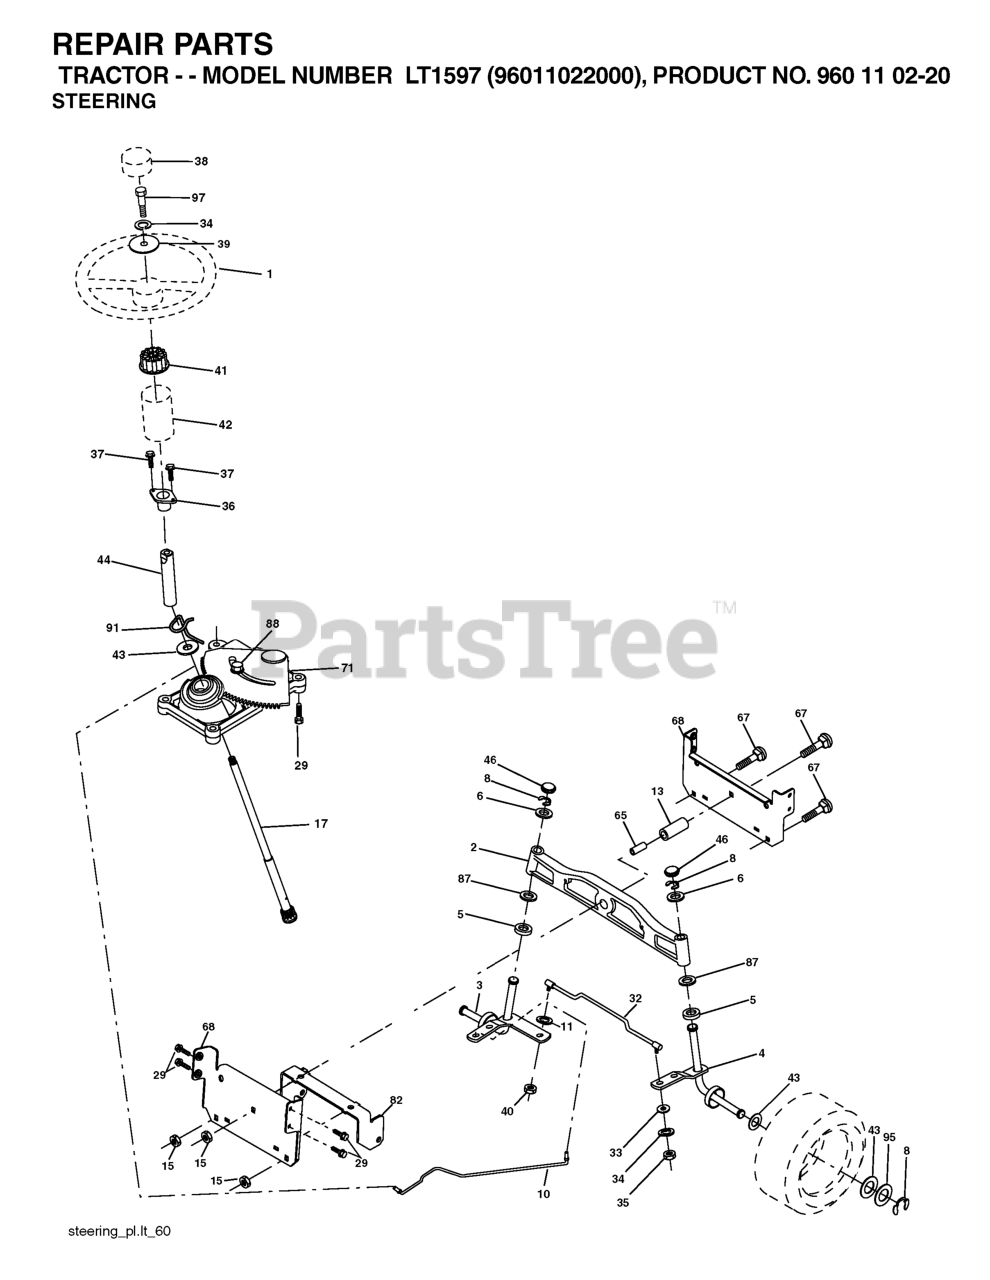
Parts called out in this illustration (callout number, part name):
1	WHEEL.STEERING.LEGEND2.GRY
2	AXLE ASSY FRONT
3	SPINDLE.ASM.LH.15"TIRES
4	SPINDLE.ASM.RH.15"TIRES
5	THRUST WASHER
9	BRNG T
10	DRAGLINK.15".TIRES.2001
11	WASHER, LOCK 3/8
13	TUBE, PIVOT AXLE
15	NUT
17	SHAFT STEERING SPLINE
29	SCREW, 3/8-16X3/4
33	WASHER M
34	WASHER.LOCK.HVY.HLCL.SPR.5/16
35	NUT, CROWNLOCK
36	BUSHING, STEERING
37	SCREW.TT.#10-32X.5.3/8.FLANGE
38	INSERT.CAP.STRG.WH.GRAY
39	WASHER.11/32
40	NUT CROWNLOCK 3/8-24
41	ADAPTER, WHEEL STNG..
42	BOOT STEERING
44	SHAFT.EXTEN.STRG.SPLINE
46	CAP.SPINDLE.BLACK
47	FITTING.GREASE.TAPERED
65	SPACER BRACE AXLE
67	BOLT CARRIAGE
68	BRACE.AXLE.15"TIRES
71	STEERING ASM
82	BRACKET.SUSP.CHASSIS.FRONT.15
87	WASHER, FLAT .781 X 1 1/2"
88	BOLT, SHOULDER 7/16-20
91	CLIP.STEERING
95	WASHER.HARDENED
